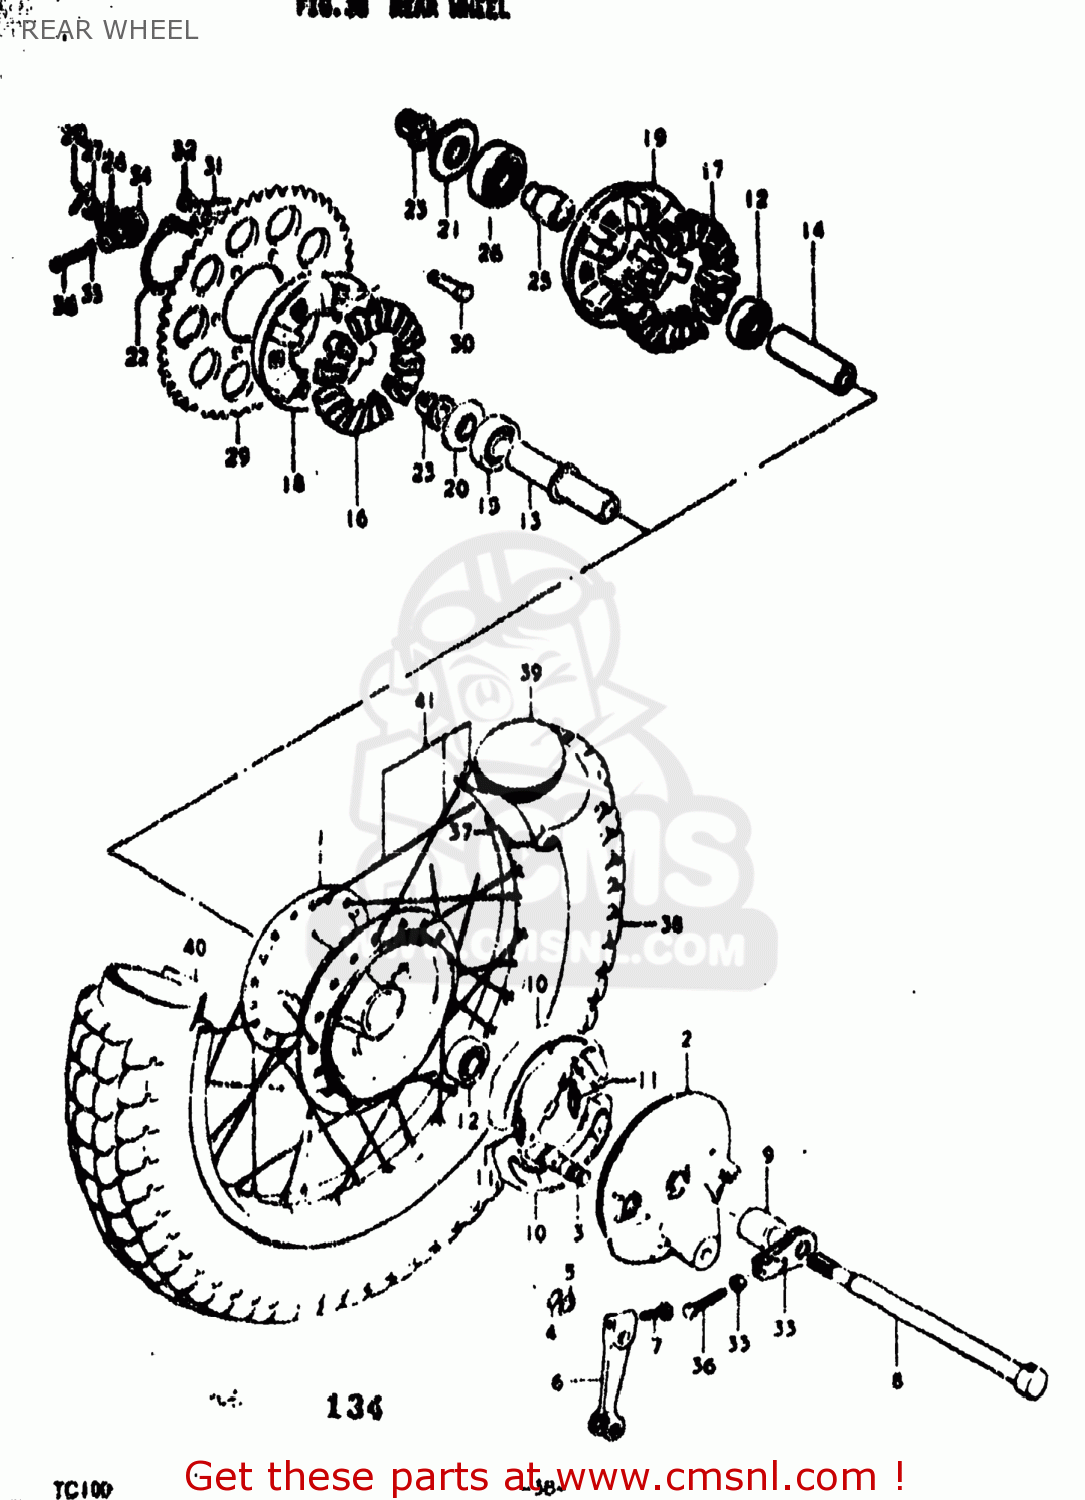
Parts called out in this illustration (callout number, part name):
1	HUB,REAR
2	PANEL,REAR HUB
3	CAM,FRONT BRAKE
4	O RING(D:2.5,ID:11.4)
5	WASHER(12.5X20X1)
6	LEVER,REAR BRAKE CAM
7	BOLT
8	AXLE,REAR
9	SPACER
10	SHOE,BRAKE
11	SPRING(L:34)
12	BEARING
13	SPACER,REAR HUB BEARING
14	SPACER
15	BEARING
16	ABSORBER,RR WHEEL HUB SHOCK
17	ABSORBER,RR WHEEL HUB SHOCK
18	DRUM,REAR SPROCKET MOUNT
19	DRUM,REAR SPROCKET MOUNT
20	SPACER,REAR HUB BEARING
21	SPACER,REAR AXLE,RIGHT
22	CIRCLIP
23	SPACER,CHAIN ADJUSTER,L
24	NUT
25	SPACER,REAR HUB BEARING
26	BEARING
27	NUT 12MM
28	COTTER PIN
29	SPROCKET,REAR
30	BOLT(8X32)
31	WASHER
32	NUT
33	ADJUSTER,CHAIN
34	ADJUSTER,CHAIN
35	NUT
36	BOLT
37	RIM,REAR WHEEL
38	TIRE
39	TUBE,INNER
40	PROTECTOR,INNER TUBE
41	SPOKE SET,REAR
